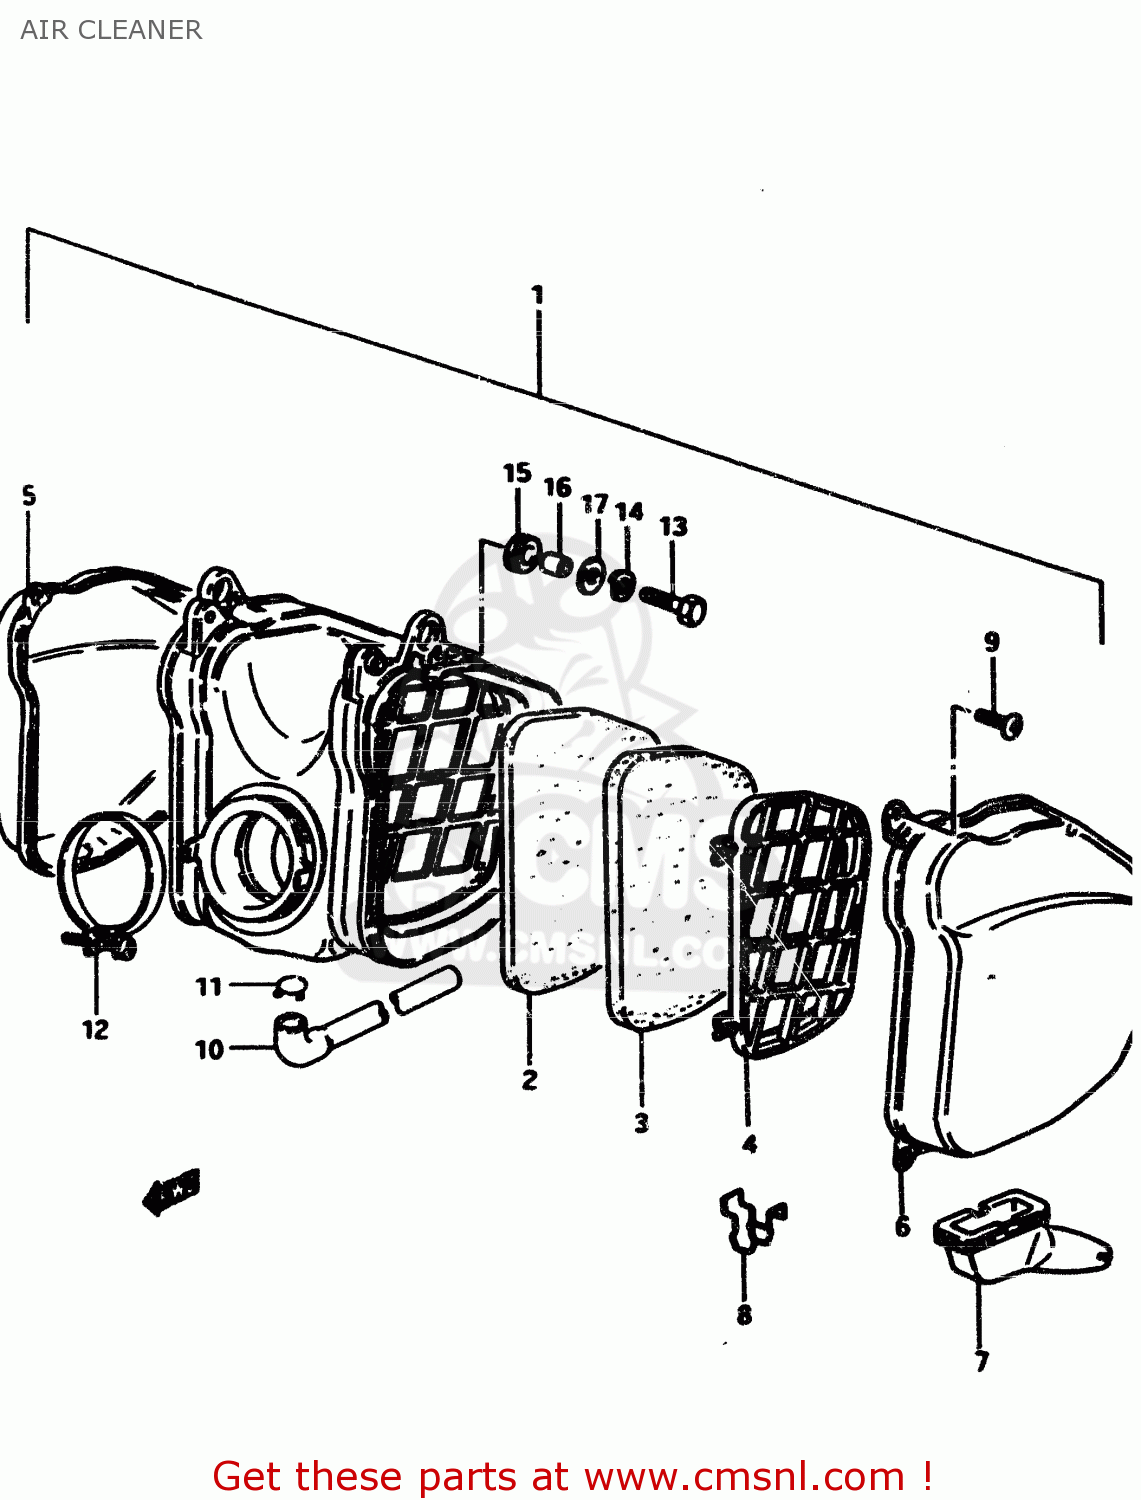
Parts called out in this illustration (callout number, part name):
1	CLEANER ASSEMBLY,AIR
2	FILTER
3	FILTER,2ND
4	HOLDER,AIR CLEANER,LEFT
5	CAP,AIR CLEANER,RIGHT
6	CAP,AIR CLEANER,LEFT
7	DRAIN TUBE
8	DRAIN STOPPER
9	SCREW
10	DRAIN TUBE
11	CLIP
12	CLAMP
13	BOLT
14	LOCK WASHER
15	CUSHION
16	SPACER (7X9X7)
17	WASHER
